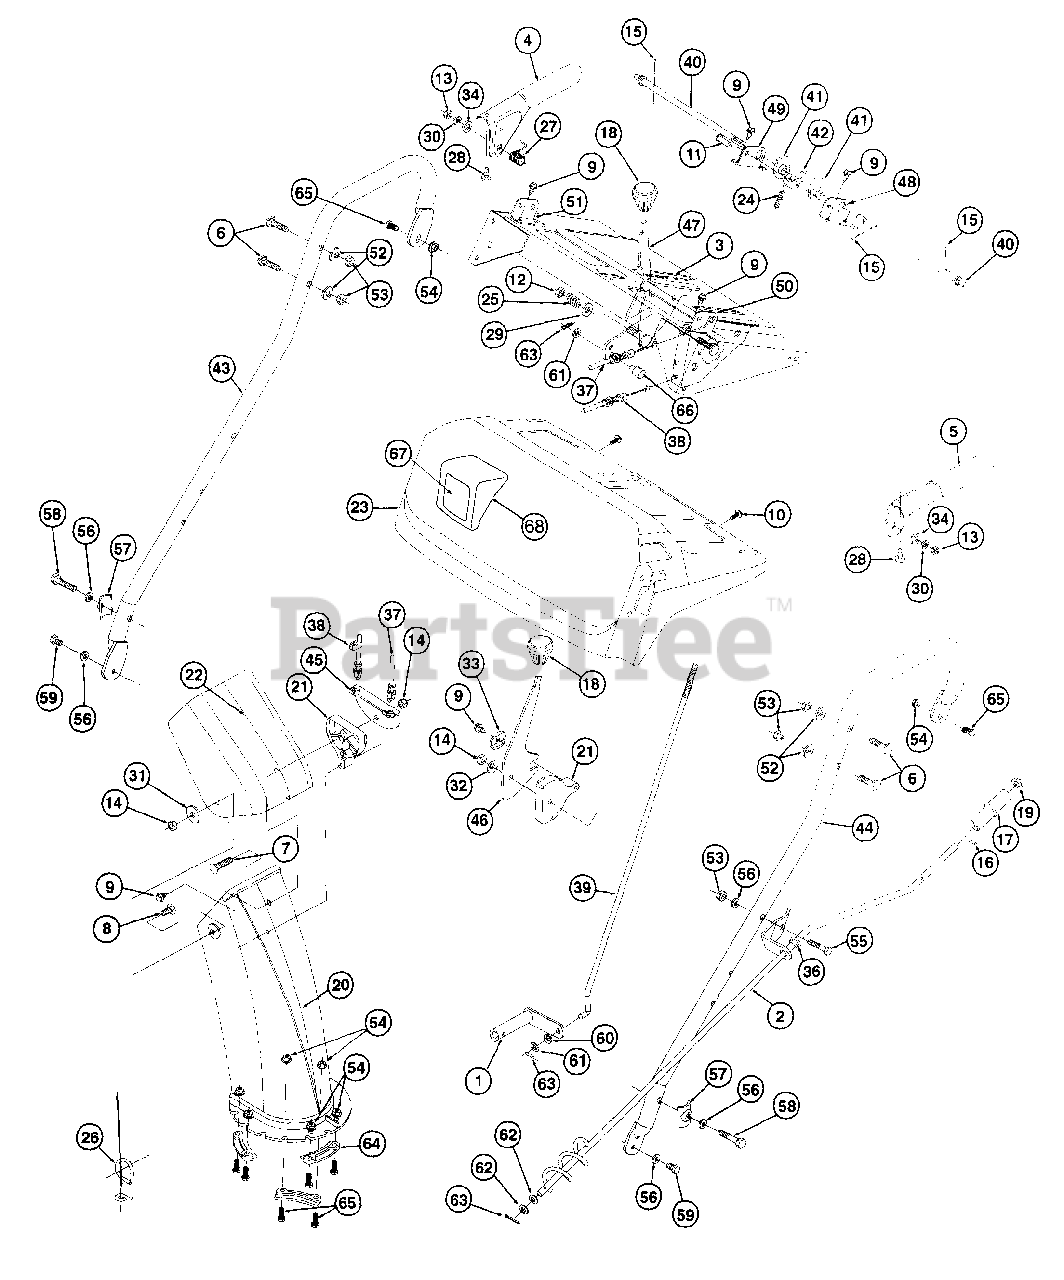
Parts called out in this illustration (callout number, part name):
1	Shift Arm Assembly
2	Chute Crank Assembly
5	Handle Assy. Engagement LH
6	Carriage Bolt
7	Carriage Bolt
8	Carriage Bolt
9	Hex Screw
10	Tapp. Screw
11	Clevis Pin
12	Lock Nut
13	Hex Nut
14	Hex Patch Lock Nut
15	Cotter Pin
16	Rolling Pin
17	Chute Crank Knob
18	Shift Knob
19	Push Cap
20	Lower Chute
21	Cable Guide
22	Upper Chute
23	Handle Panel
24	Compression Spring
25	Compression Spring
26	Cable Control Wire
27	Torsion Spring
28	Rubber Bumper
29	Bell Washer
30	Lock Washer
31	Washer
32	Bell Washer
33	Washer
34	Washer
36	Plastic Bushing
37	Control Cable
38	Chute Deflector Cable
39	Shift Rod
40	CAM Rod
41	CAM Handle Lock
42	Pawl Handle Lock
43	RH Handle
44	LH Handle
47	Shift Handle
52	Cupped Washer
53	Hex Nut
54	Hex Flange Nut
55	Hex Bolt
56	Lock Washer
57	Handle Tab
58	Hex Bolt
59	Hex Bolt
60	Spring Washer
61	Flat Washer
62	Flat Washer
63	Hairpin Clip
64	Chute Flange Keepers
65	Hex Bolt
66	Ferrule
67	Headlight
68	Bezel
